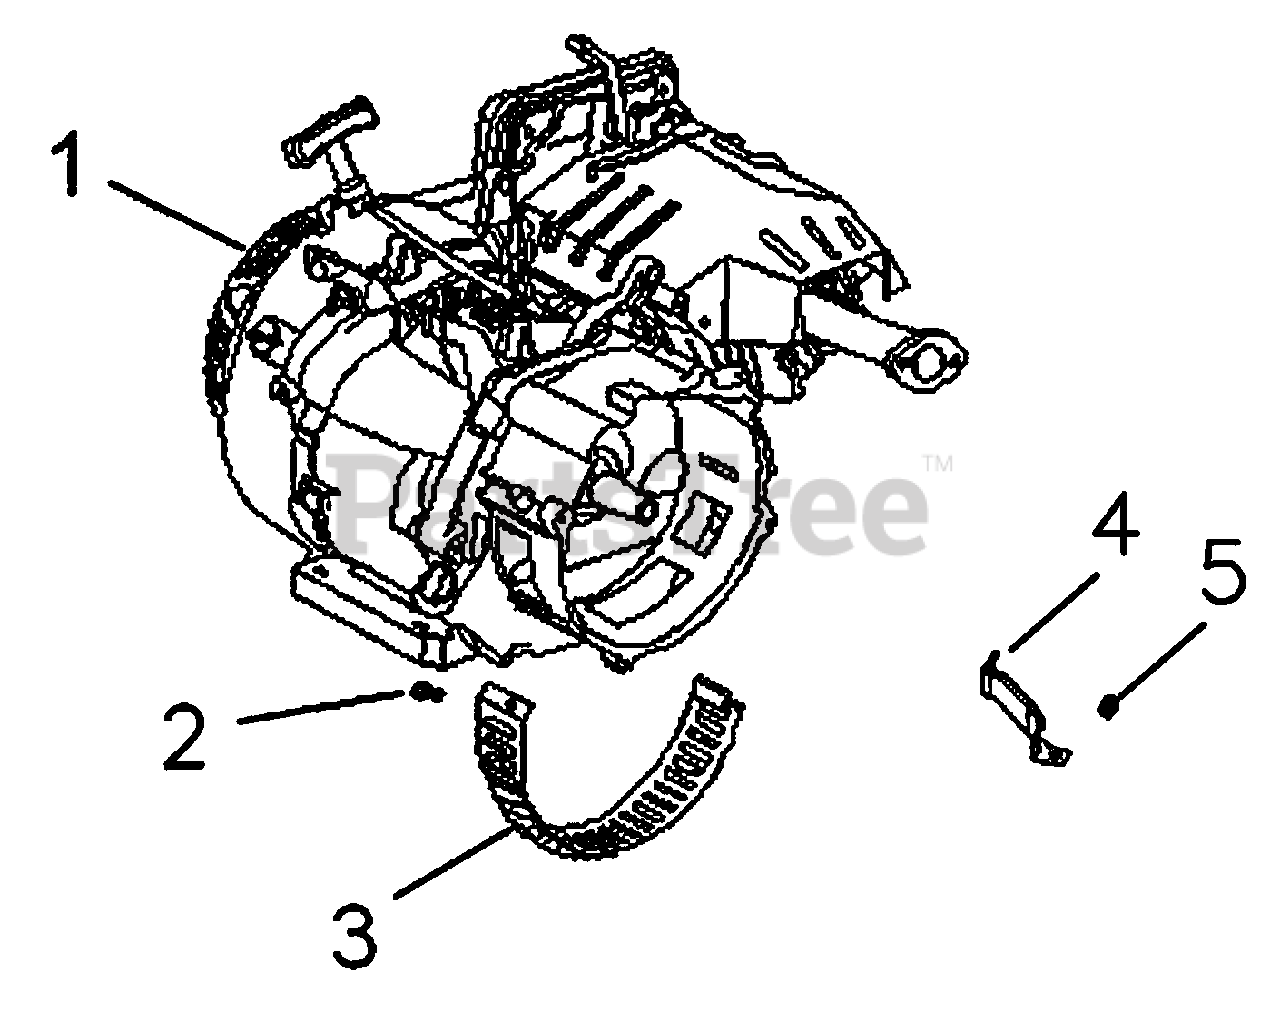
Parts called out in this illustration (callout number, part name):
1	ENGINE G420FDA
2	BOLT, FLANGE M5*10
3	ALTERNATOR SCROLL GP
4	BRACKET,AIR CLEANER
5	NUT, FLANGE M6
